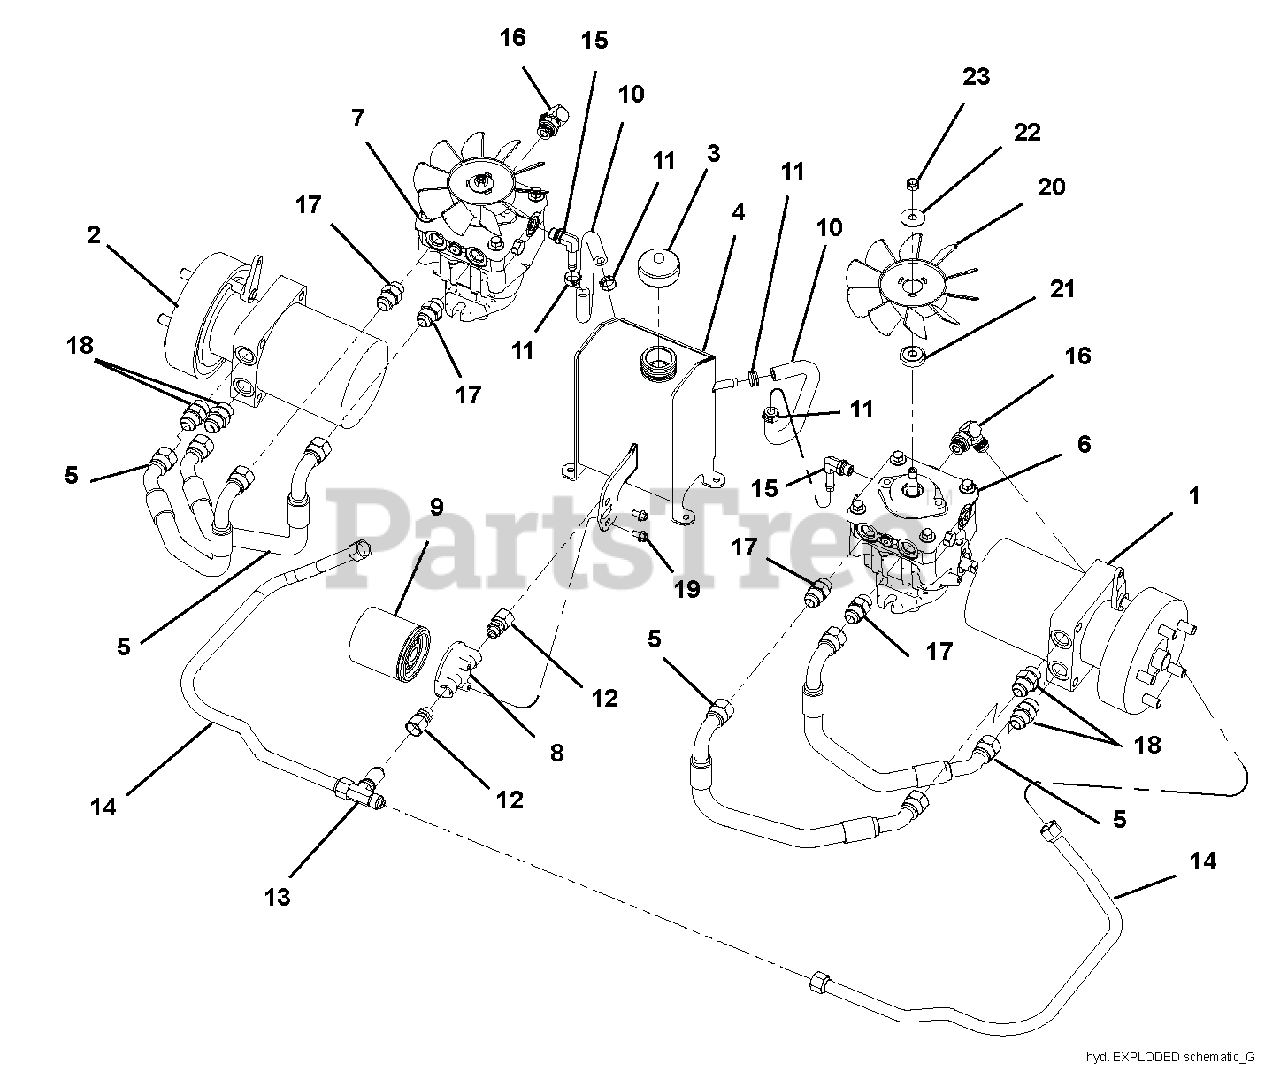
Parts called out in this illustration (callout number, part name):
1	MOTOR, LH HYDRO GEAR WHEEL
2	MOTOR, RH HYDRO GEAR WHEEL
3	CAP, OIL RESIVOIR W/FREE FLOW
4	WLDT, OIL TANK
5	HOSE, HYD-10 -10FJIC90/45 18
6	PUMP, HYDRO LH PR-2HDD
7	PUMP, HYDRO RH PR-2KDD
8	HEAD, OIL FILTER
9	FILTER, 25 MICRON
10	HOSE, HYD 3/8 X 12.50
11	CLAMP, HOSE - 11/16 SPRING
12	FTG, ADP 9/16-18MORX3/4-16FJIC
13	FTG, TUN 3/4-16JIC
14	HOSE, HYD-8 -12FJIC 29
15	FTG, 90 9/16MOR X 3/8HOSE
16	FTG, 90 ADP JIC-ORB 6801-08-08
17	FTG, ADP 3/4MORX7/8MJIC
18	FTG, ADP 7/8-14MORX7/8-14FJIC
19	BOLT, 1/4-20X.500 WSH 5 Y
20	FAN, BDP16 PLASTIC COOLER
21	HUB, BDP16 FAN
22	WASHER, .375X1.25X.072 BLVL U
23	LOCKNUT, 3/8-24 CROWN Y
24	LEVER S/0
25	KIT, MOTOR SEAL - DF280 S/O
26	LEVER, BRAKE HYDRO GEAR S/O
27	Seal, Kit Wheel Motors, Hydro-Gear (Serial Number 101 - 2499)
